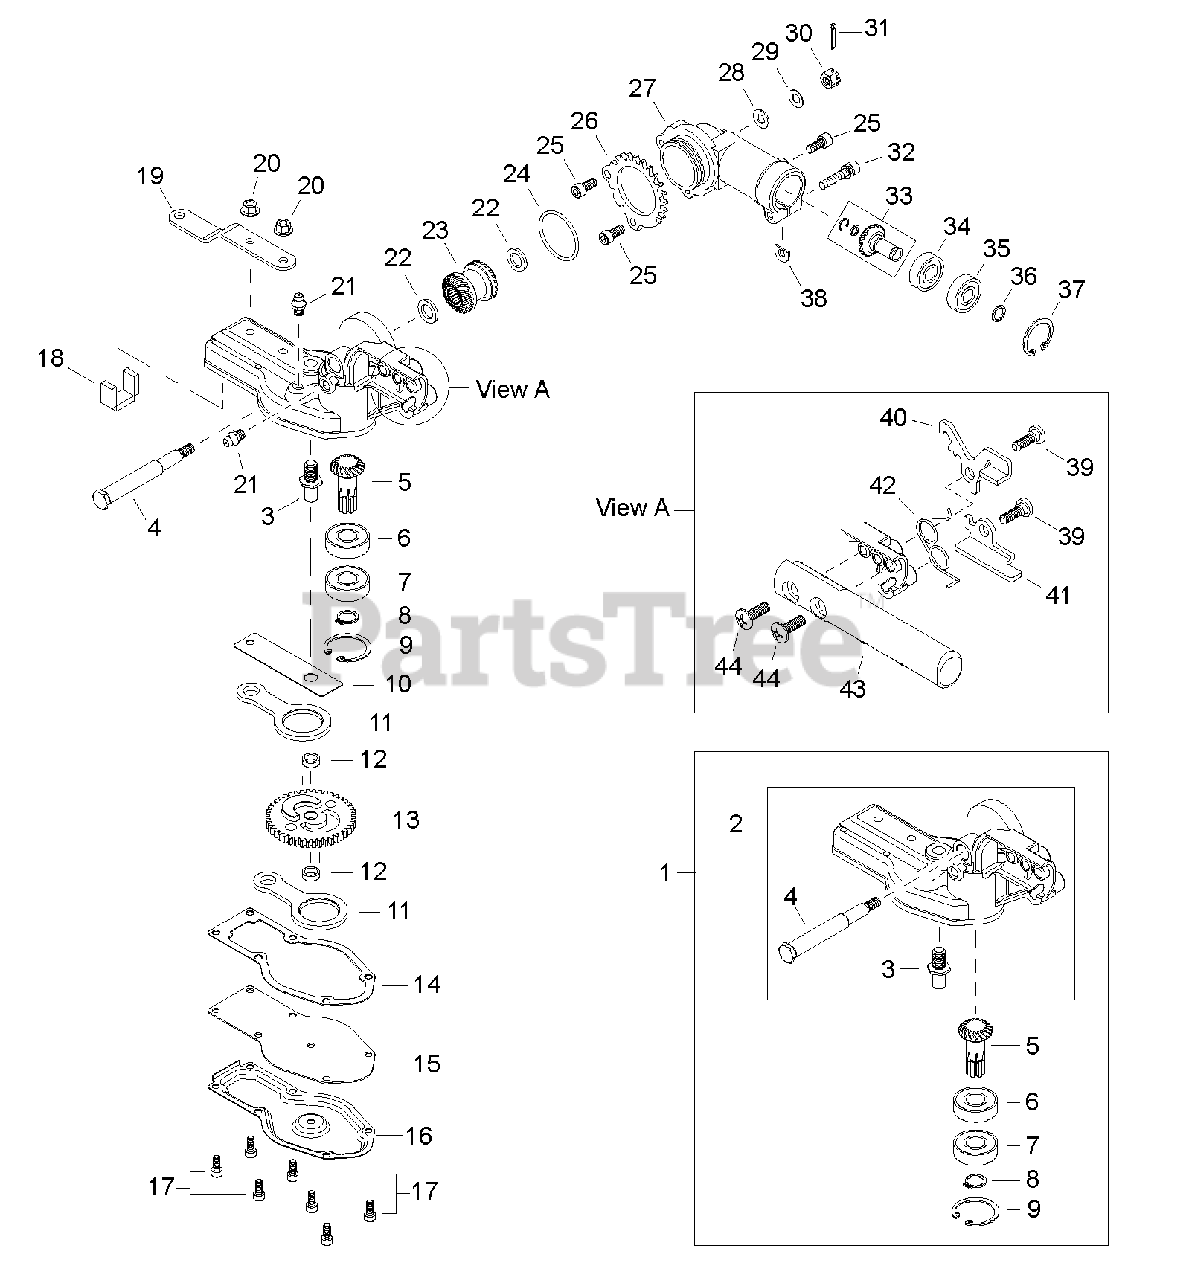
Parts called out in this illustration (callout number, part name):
1	GEAR CASE ASSY
2	CASE, GEAR - LOWER
3	PIPE, MAIN
4	SHAFT
5	GEAR - SHAFT
6	BEARING, BALL - 6001
7	BEARING, BALL - 6001ZZ
8	RING, RETAINING - 12
9	RING, RETAINING - 28
10	PLATE, GUIDE
11	ROD, CONNECTING
12	SPACER
13	CAM GEAR
14	GASKET
15	PLATE, GEAR CASE
16	CASE, GEAR - LOWER
17	SCREW - 4X10
18	SEAL, FELT
19	BRACKET, CUTTER
20	NUT - 5 -- FLANGE
21	FITTING, GREASE
22	COLLAR
23	GEAR SET - BEVEL
24	O-RING
25	SCREW - 5X12
26	PLATE, ADJUST
27	CASE, GEAR - UPPER
28	WASHER - 6
29	WASHER - CONICAL
30	NUT - CASTLE
31	PIN, SPLIT
32	SCREW - 5X25
33	GEAR - BEVEL
34	BEARING, BALL - 609
35	BEARING, BALL - 609ZZ
36	RING, RETAINING
37	RING, RETAINING - 24
38	SHIM
39	SCREW
40	LEVER, LOCK
41	LEVER, LOCK
42	SPRING
43	LEVER, ADJUSTMENT
44	SCREW - 6X20
